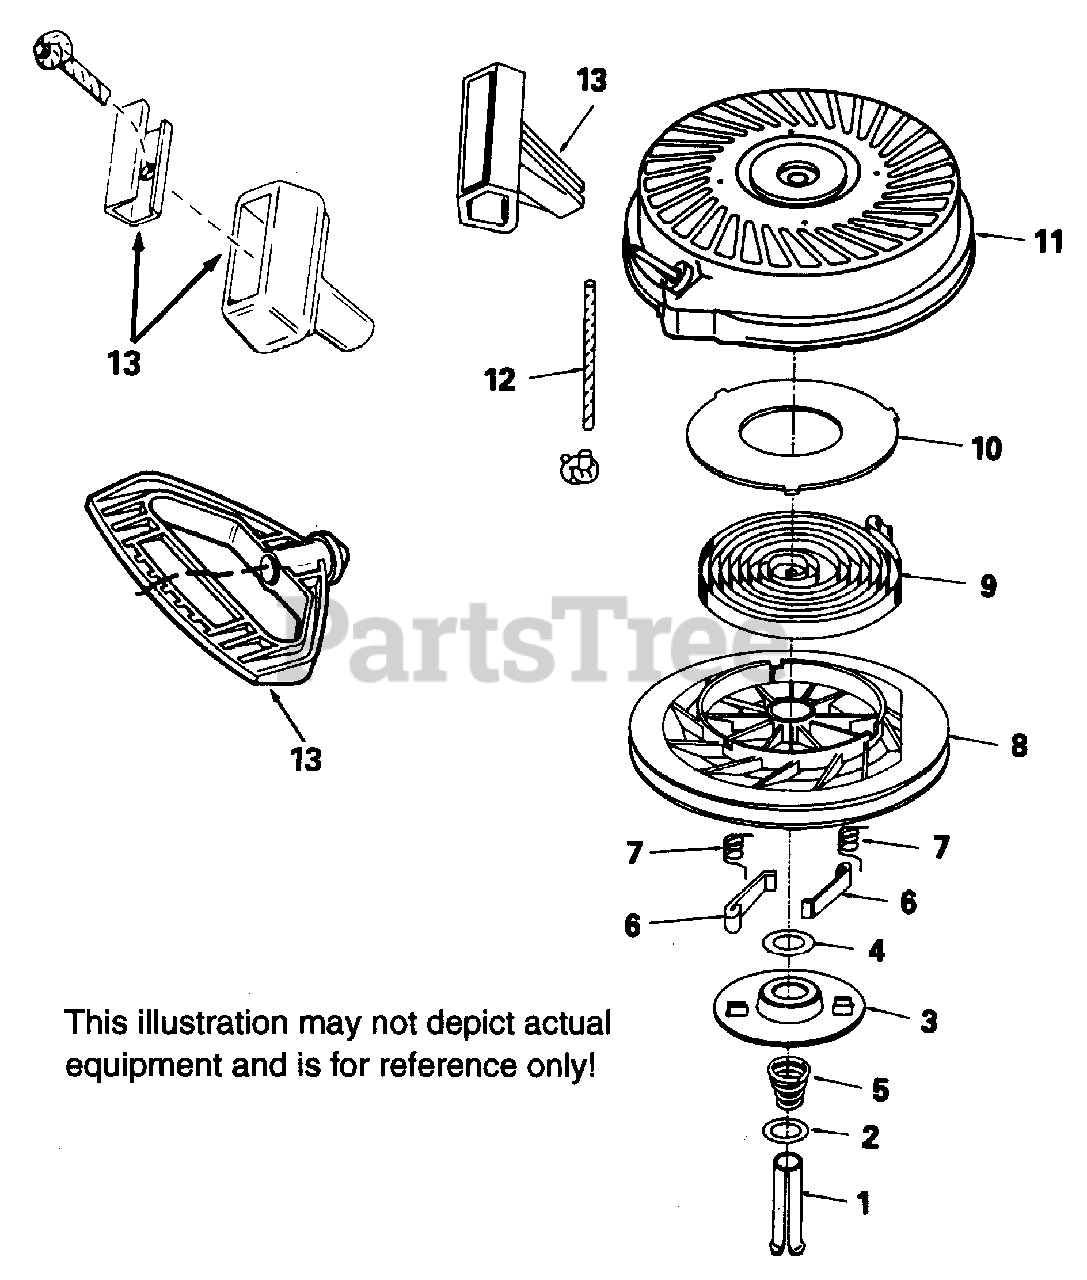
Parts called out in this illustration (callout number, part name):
1	Spring Pin (Incl. 4)
3	Retainer
5	Brake Spring
6	Starter Dog
7	Dog Spring
8	Pulley Ass'y. (Incl. 9 & 10)
9	Rewind Spring
10	Spring Cover
11	Starter Housing Ass'y.
12	Starter Rope also available in 740033 B Starter Rope & Handle Kit
13	Starter Handle
